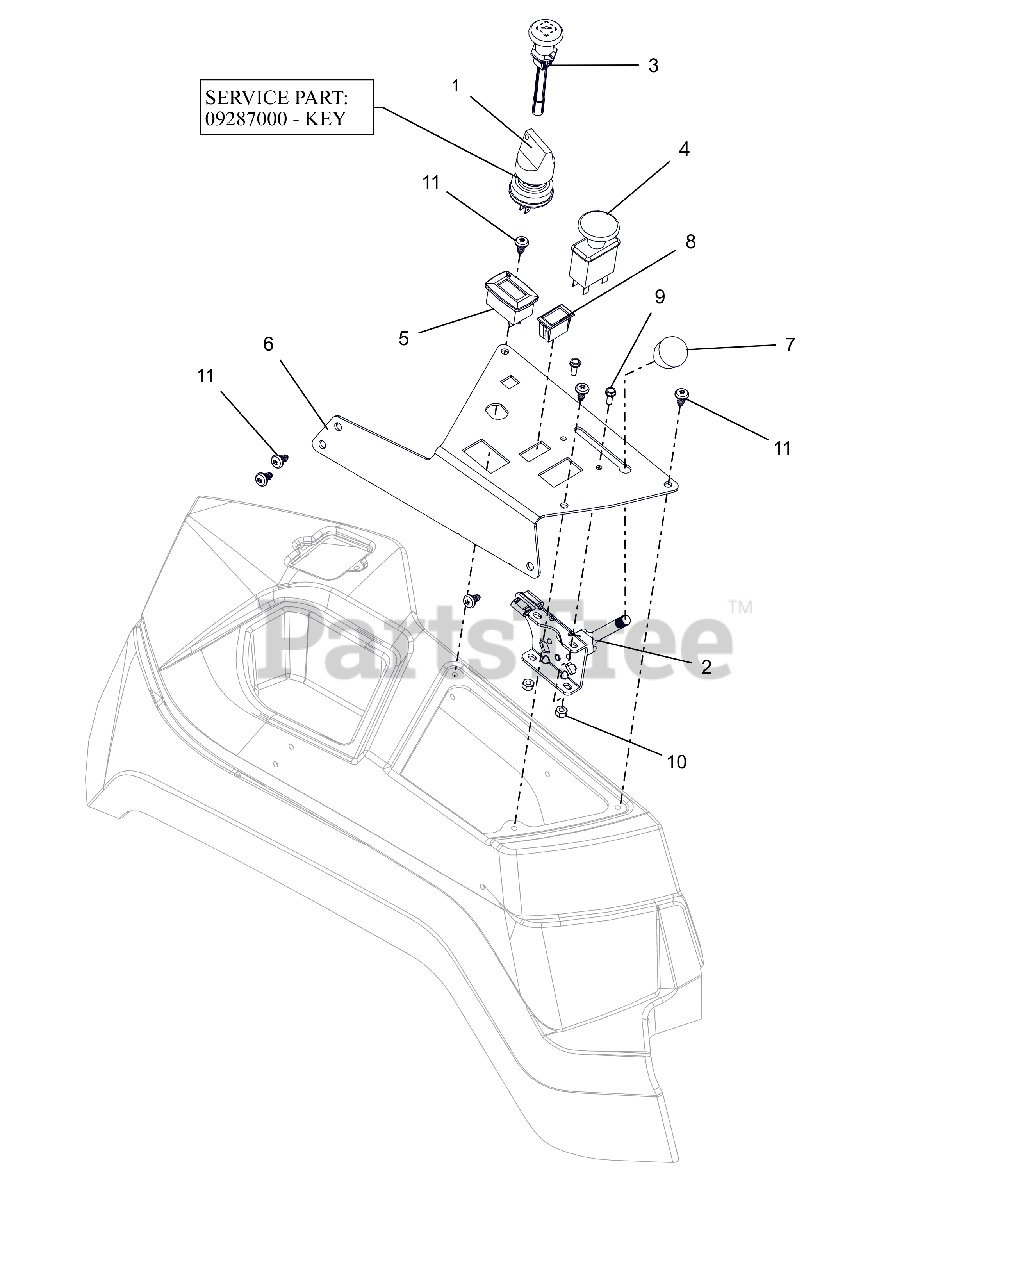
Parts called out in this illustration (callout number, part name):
1	SWITCH, IGNITION
1	KEY, W/ SHIELD
2	CABLE, PRO THROTTLE CONTROL
3	CABLE - CHOKE, SNAP-IN
4	SWITCH, CLUTCH
5	METER, HOUR W/MAINTENANCE
6	PLATE, APEX CONTROL PANEL
7	KNOB-CONTROL-BLACK .38-16X.50
8	SWITCH,BLANK
9	BLT, HWH #10-24X.50 ZCC
10	NUT-LK-NYL #10-24 G2 ZCC
11	SCR-PAN .25-15X.50 6L H/LZB500
